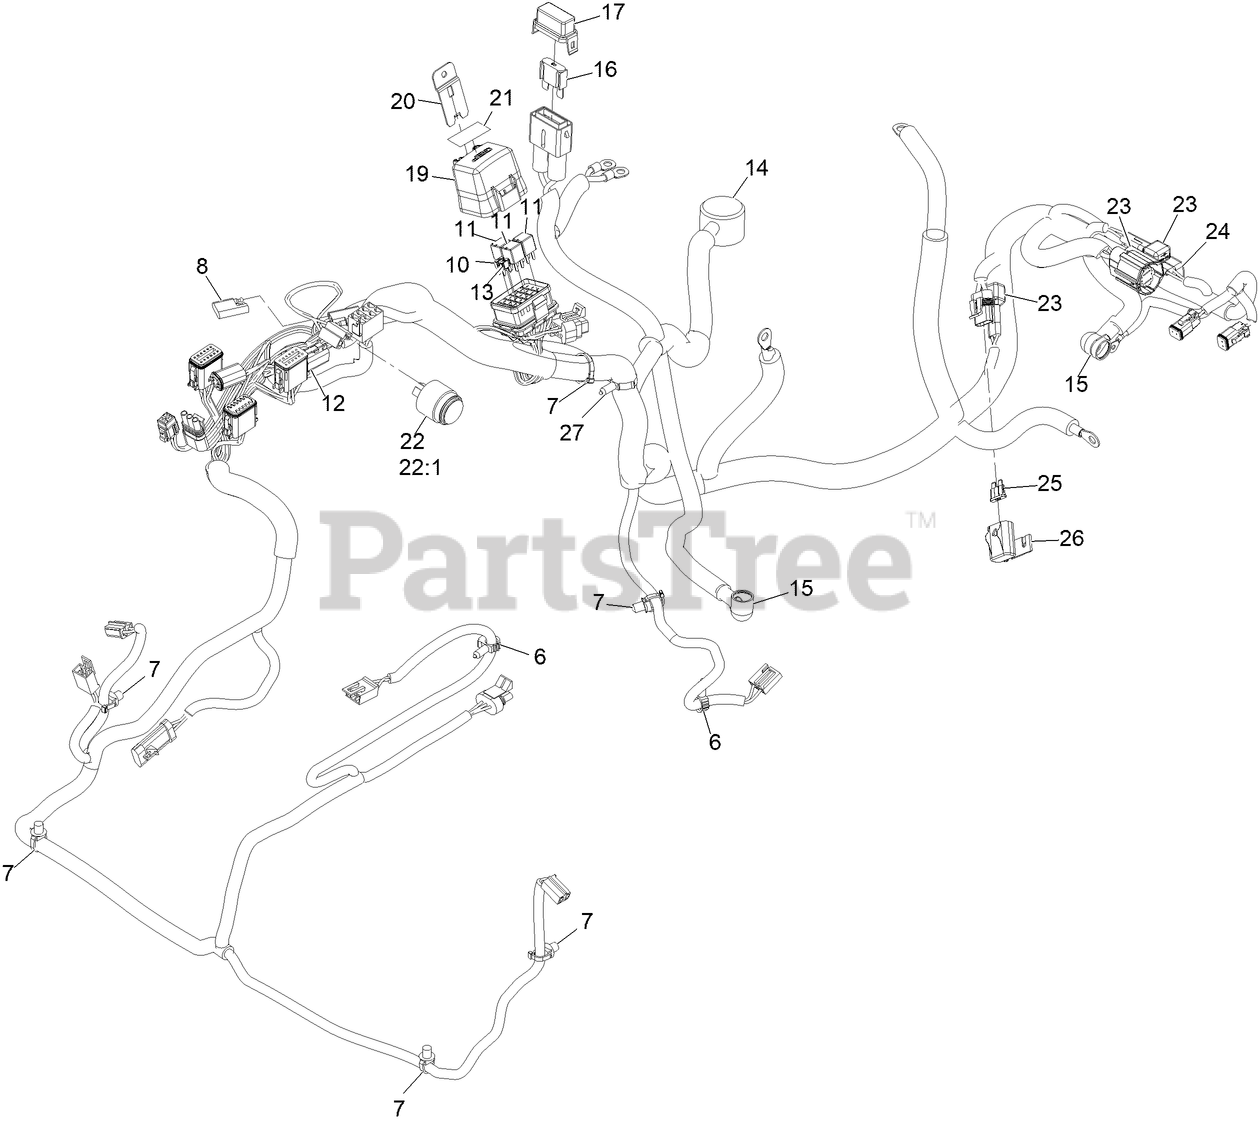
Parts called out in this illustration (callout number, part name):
6	CLIP-HARNESS
7	CLIP-TIE
8	Cap-Plug
10	FUSE-MINI BLADE, 20 AMP
11	RELAY-MICRO
12	CAP-PLUG, 6 WAY
13	FUSE-MINI BLADE, 15 AMP
14	INSULATOR-BATTERY
15	INSULATOR-SOLENOID
16	FUSE-BLADE, 50 AMP
17	Cover-Fuse Holder, Maxi
19	Cover-Fuseblock, 24F, Gep
20	CLIP-MOUNTING
21	Decal-Fuse
22	Audio Alarm ASM
22:1	Nut-Plastic, Knurled
24	Resistor - 30K Ohms 5% Overmolded
25	Fuse-40 Amp
26	Cover-Fuse, Single
27	Clip-Harness,Tubing (16MM)
